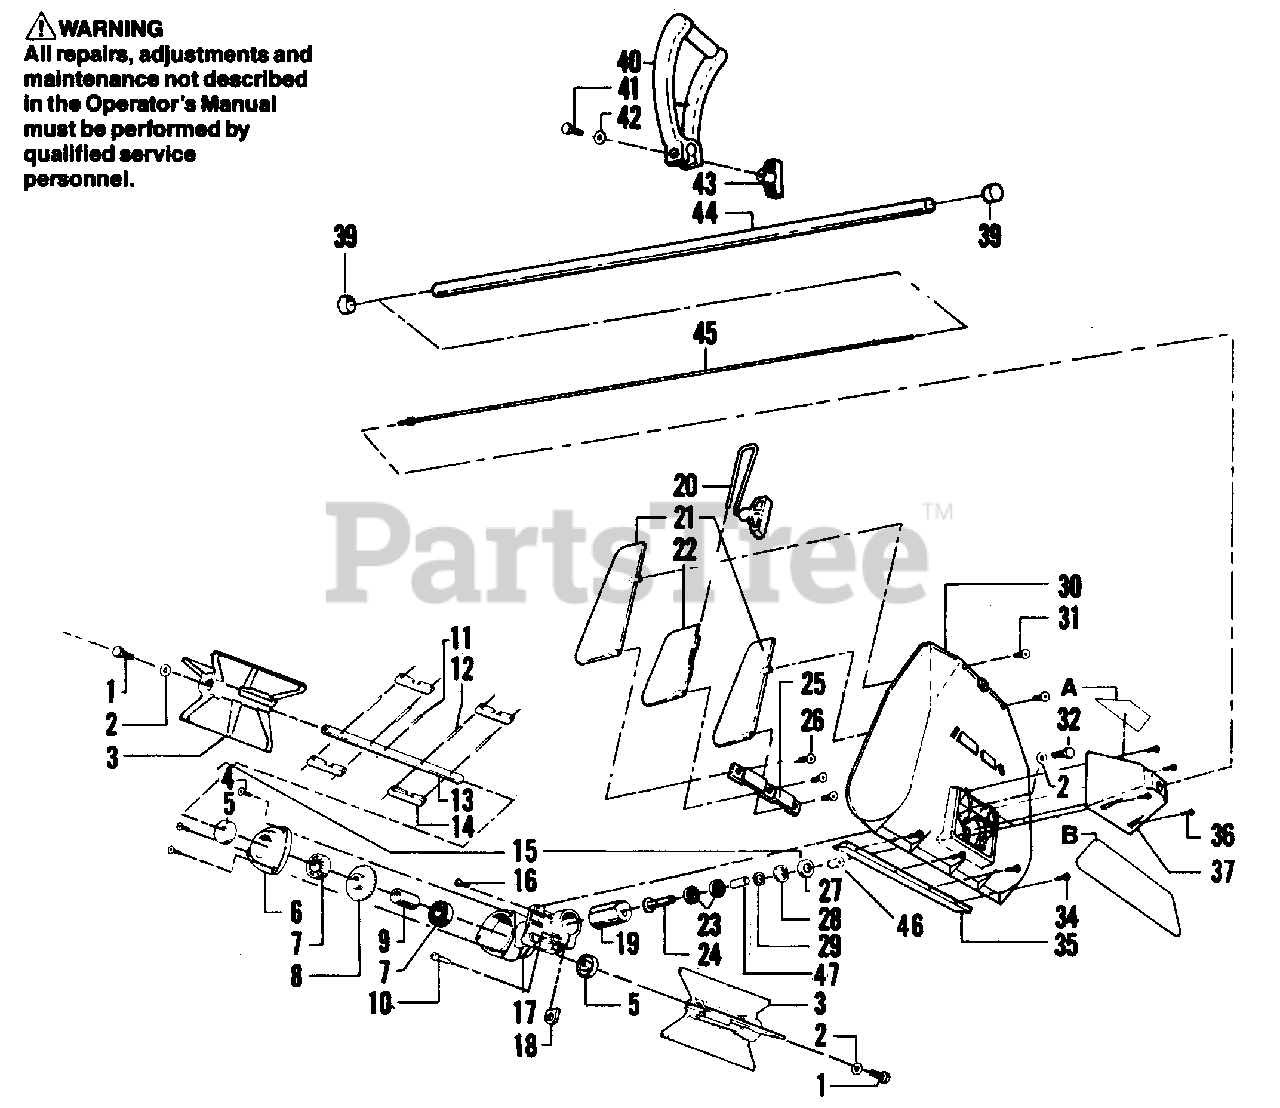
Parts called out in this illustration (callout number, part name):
1	Screw - Impeller - 1/4 - 20 x 1/2 - Hex Hd.
2	Washer - Impeller & Gear Box Mounting
3	Impeller
4	Screw - Gear Housing
5	Oil Seal - Double Lip
6	Gear Housing Cover
7	Bearing - Shaft
8	Gear - Spiral Bevel
9	Collar - Shaft
10	Screw - Pinch Clamp - 1/4 - 20 x 1/2 - Hd.
11	Pin Spiral - Gear
12	Pin - Spiral - Brace
13	Output Shaft
14	Brace - Impeller
15	Gear Box Assembly (Inc. #4-10, 16-19, 23, 24 & 27-29)
16	Screw - Index 10 - 24 x 7/16
17	Gear Housing
18	Washer - Fiber Filler
20	Activating Rod Assembly
21	Vane - Outboard
22	Vane - Center
23	Bearing - Pinion
24	Pinion Gear - Forged Bevel
25	Tie - Bar - Vane (obsolete)
26	Screw - Vane Tie Bar - 8 - 16 Soc. Hd.
27	Oil Seal - Single Lip
28	Retaining Ring
29	Retaining Ring - Pinion
30	Housing -Impeller
31	Screw - Vane - 18 - 16 Socket Hd.
32	Screw - Gear Box Mounting
34	Screw - Scraper Bar - 8 - 12 x 3/4 - Fil Hd.
35	Scraper Bar
36	Screw - Rear Cover - 8 - 12 x 3/4 - Fil Hd.
37	Cover - Rear
39	Cap - Drive Shaft Housing
40	Assist Handle
41	Screw - Assist Handle
42	Washer - Assist Handle
43	Knob - Assist Handle
44	Drive Shaft Housing (Inc. #45)
45	Drive Shaft
46	Plug - Grease
47	Collar Pinion
A	Decal - Weed Eater - Rear Cover
B	Decal - Directional Control
